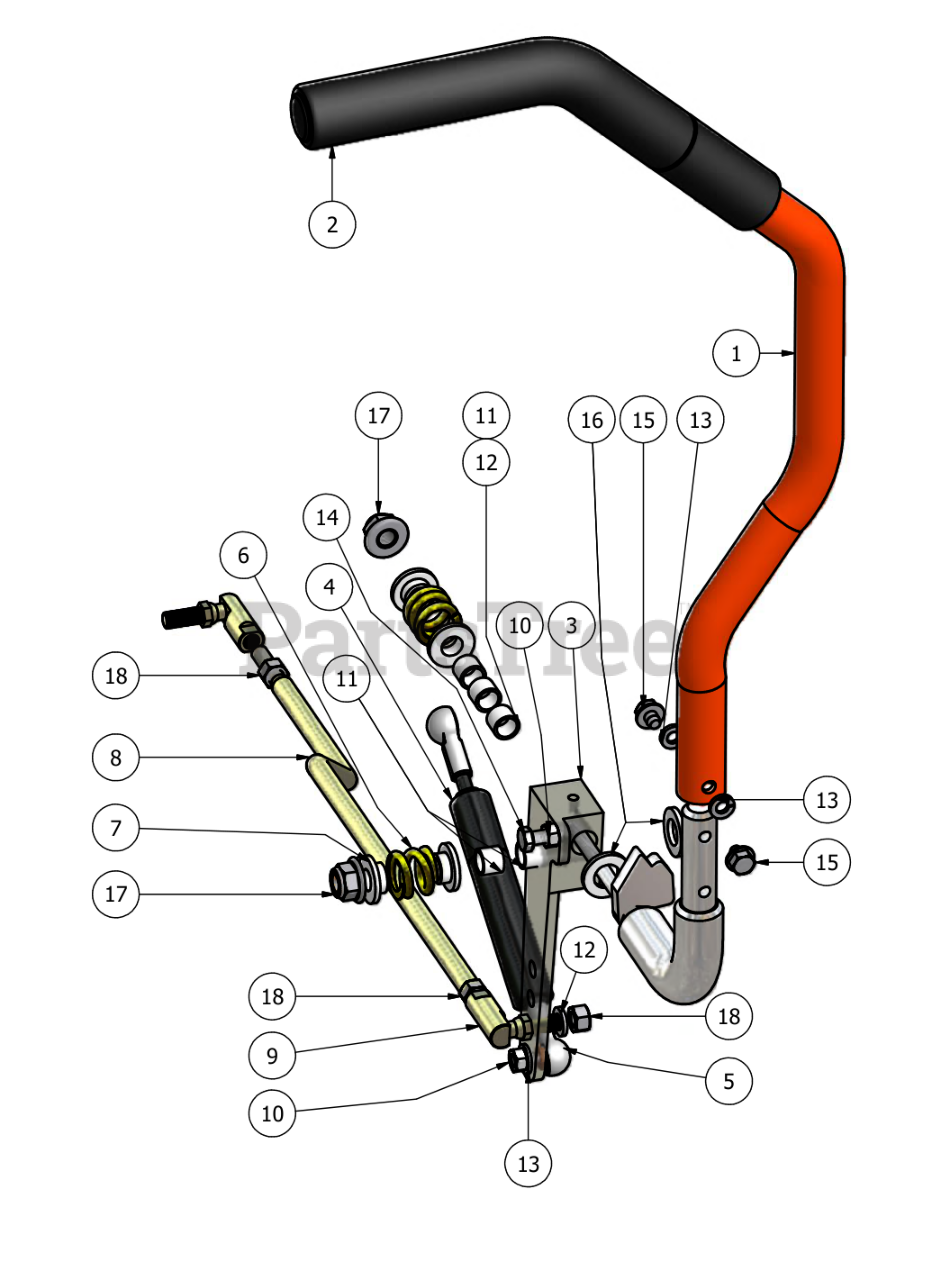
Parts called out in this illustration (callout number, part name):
1	Right Drive Arm
1	Left Drive Arm
2	Rubber Steering Handle
3	Left Drive Arm Lever Housing
3	Right Drive Arm Lever Housing
5	10MM Damper Ball Stud
6	Drive Lever Spring
7	.515 ID Nylon Shoulder Washer
9	3/8-24 Ball joint (female/male)
11	.507 ID Nylon Bushing
12	3/8" Lock Washer
13	5/16" Lock Washer
14	5/16" x 3/4" Hex Bolt
15	5/16" x 1/2" Flange Bolt
16	.505 ID Plastic Washer
17	1/2" Flange Lock Nut
18	3/8" Fine Thread Nut
